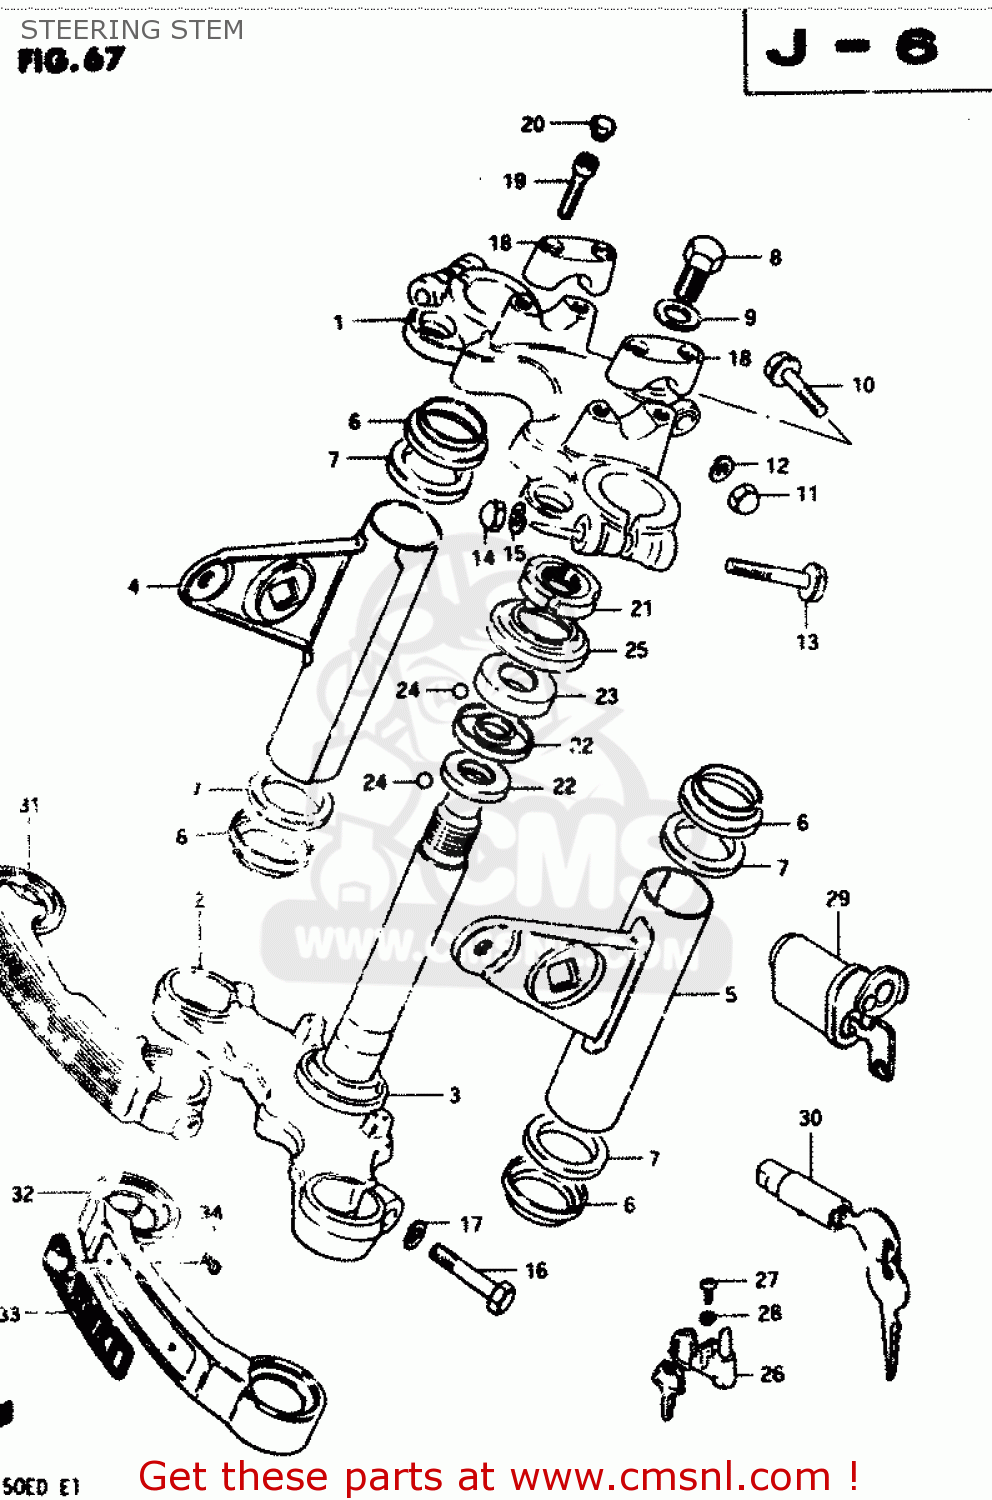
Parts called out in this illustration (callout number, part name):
1	HEAD,STEERING STEM
2	STEM,STEERING
3	RACE,STEERING OUTER LWR
4	BRACKET,HEADLAMP,RIGHT
5	BRACKET,HEADLAMP,LEFT
6	CAP,HEADLAMP BRACKET
7	CUSHION,HEADLAMP BRACKET
8	BOLT(12X20)
9	WASHER (12.5X26X1.6)
10	BOLT
11	NUT
12	LOCK WASHER
13	BOLT 10X55
14	NUT
15	LOCK WASHER
16	BOLT 10X40
17	LOCK WASHER
18	HOLDER,HANDLEBAR(BLACK)
19	BOLT
20	CAP(OD:14.5)
21	NUT,STEERING STEM(25X44X10)
22	LACE,STEERING INNER LWR
23	LACE,STEERING OUTER UPR
24	BALL
25	DUST SEAL,STEERING UPR
26	LOCK ASSY,STEERING
27	SCREW
28	LOCK WASHER
29	LOCK ASSY, STEERING (NEIMAN TYPE EXECUTE
30	LOCK ASSEMBLY,STEERING (NEI
31	COVER,FRONT FORK
32	COVER,FRONT FORK
33	EMBLEM,FR FORK COVER
34	NUT
